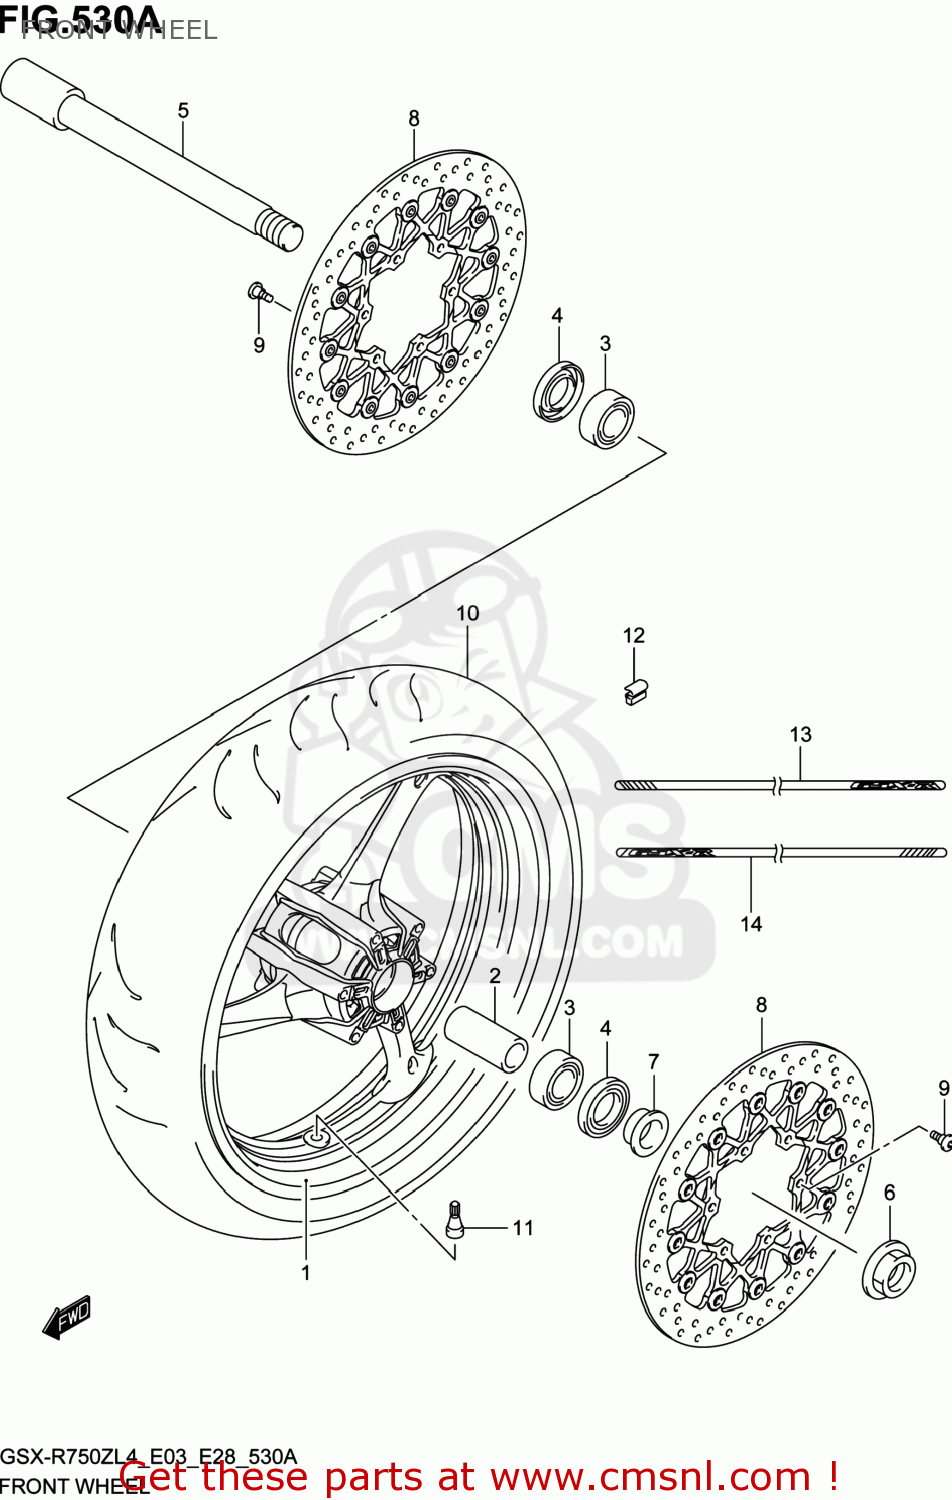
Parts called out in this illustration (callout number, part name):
1	WHEEL,FR(17M/CXMT3.50)
2	SPACER,FR HUB BEARING
3	BEARING(22X44X12)
4	SEAL,OIL(28X44X7.5)
5	AXLE,FR
6	NUT,RR SHOCK ABS BRACKET
7	SPACER,FR AXLE,L
8	DISC,FR BRAKE
9	BOLT(6X21)
10	TIRE,FR
11	VALVE ASSY,WHEEL RIM(TR412)
12	BALANCER,WHEEL(10G)
13	TAPE,WHEEL FRONT,R
14	TAPE,WHEEL FRONT,L
